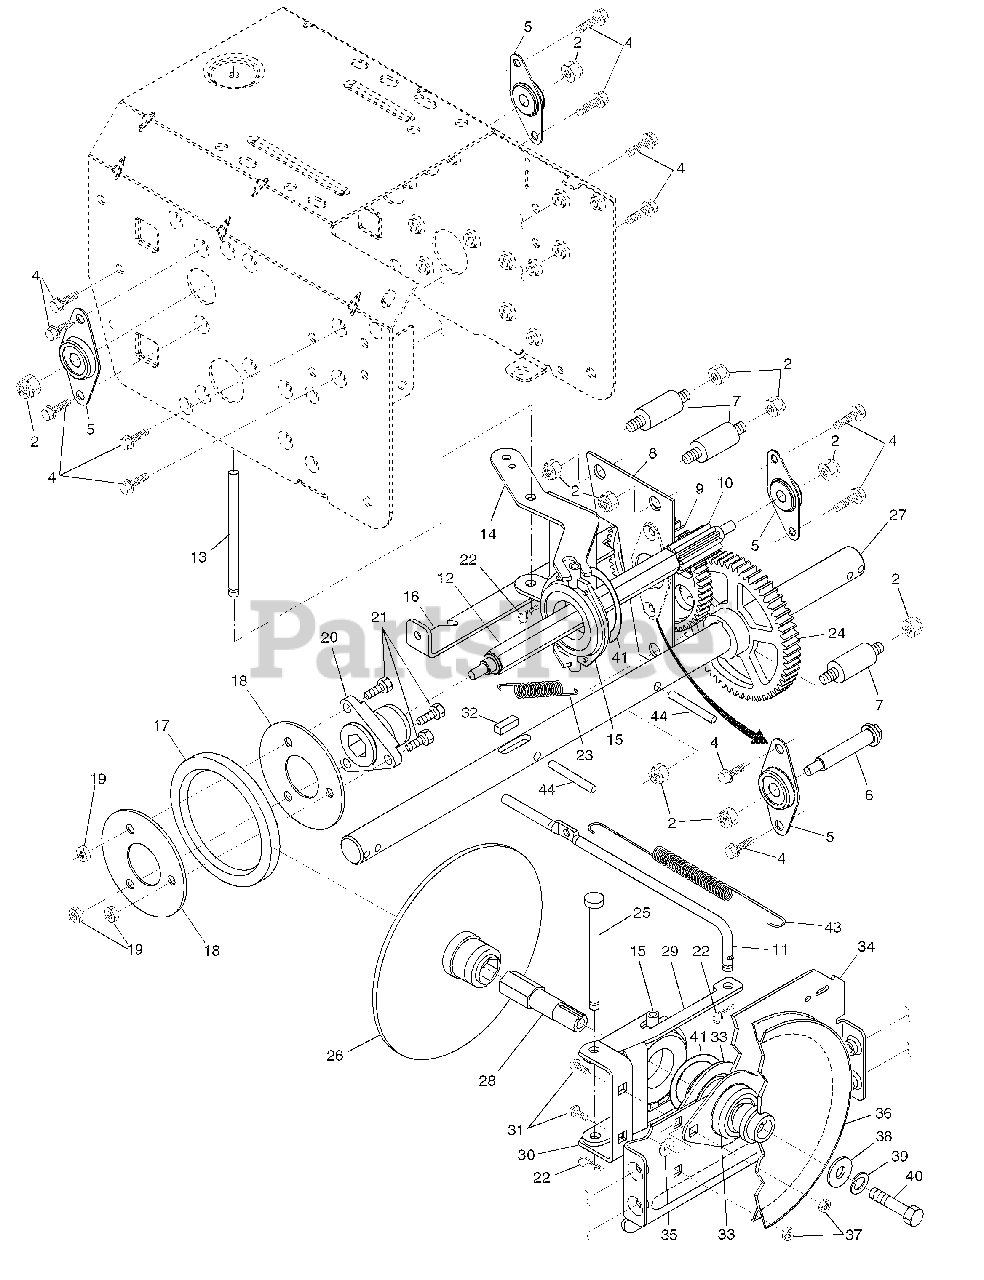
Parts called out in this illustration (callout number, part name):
1	Screw, Hex Head 5/16-18 x 3/4
2	Nut, Lock 5/16-18
4	Screw, Hex Head 5/16-18 x 1/2
5	Bearing, Flange
6	Shaft, Auxiliary
7	Spacer, Plate
8	Plate, Auxiliary
9	Gear, Intermediate
10	Gear, Pinion
11	Rod, Clutch
12	Shaft, Long, Hex
13	Pin, Pivot
14	Lever, Shifter / Wheel
15	Trunnion Bearing Assembly
16	Bracket, Pivot, Shift
17	Ring, Rubber Wheel
18	Plate, Rubber Wheel
19	Nut, Lock 5/16-18
20	Hub, Rubber Wheel
21	Screw, Hex Head 5/16-18 x 7/8
22	Retainer, Hairpin
23	Spring, Bias
24	Gear, Axle
25	Pin, Pivot Lever
26	Plate Assembly, Drive
27	Shaft, Axle
28	Shaft, Short Hex
29	Lever, Shifter Plate
30	Bracket, Shifter Support
31	Bolt, Carriage 5/16-18 x 5/8
32	Key, Square 1/4 x 1/4 x 7/8
33	Bearing, Flange
34	Plate, Drive Mounting
35	Spacer, Bearing
36	Pulley, Traction Drive
37	Nut, Lock 5/16-18
38	Washer, Flat
39	Washer, Lock 5/16
40	Screw, Hex Head 5/16-18 x 3/4
41	Ring, Retaining
43	Spring, Return
